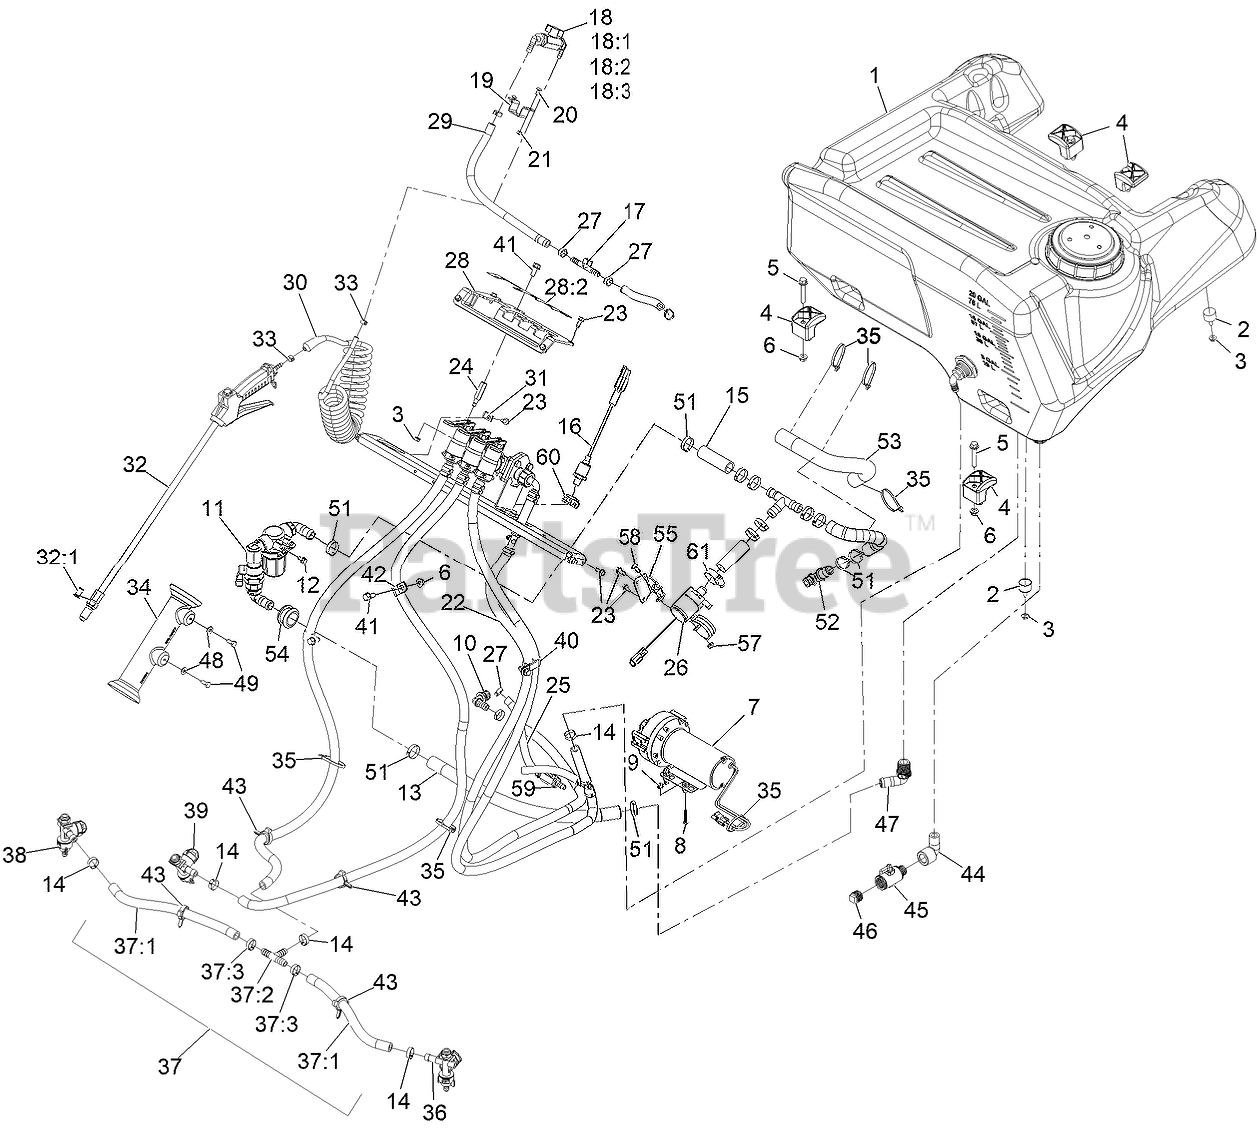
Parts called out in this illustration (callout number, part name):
1	Tank-Sprayer
5	SCREW-HHF
7	Pump-Diaphragm, 3.8 GPM
8	SCREW-SHWH
10	FITTING-ELBOW, BARBED
11	STRAINER ASM
12	SCREW-HHF
13	HOSE-WATER
14	CLAMP OETIKER 0.716"" CLOSED 0.826"" OPEN
15	ASM-, 3/4 Pvc Reinforced Water Hose
16	TRANSDUCER-PRESSURE
17	FITTING-TEE
18	Wand Control ASM
18:1	VALVE-BALL
18:2	FITTING-ELBOW-90
18:3	FITTING-ELBOW-90
19	BRACKET-VALVE
20	BOLT-CARR
21	NUT-LOCK, NI
23	SCREW-HWH
24	Spacer, Manifold Mount
25	Hose-Water
26	Pump-Centrifugal
28	COVER-CONTROLS
28:2	Decal-Lever Control
29	HOSE-WATER, 3/8 PVC RED
30	Hose-Coiled, 04X15Ft
31	CLAMP-R
32	SPRAY WAND ASM
32:1	STRAINER-NOZZLE, 50M 5PSI
34	HOLDER-WAND
35	TIE-CABLE
36	LEFT NOZZLE SUB ASM
37	HOSE ASM
37:1	HOSE-WATER
37:2	FITTING-TEE
37:3	CLAMP OETIKER 0.716"" CLOSED 0.826"" OPEN
38	RIGHT NOZZLE SUB ASM
39	CENTER NOZZLE SUB ASM
41	SCREW-HHF
42	CLIP-LOOM
43	CLAMP-HOSE
44	ELBOW-90 DEG
45	MICROVALVE
47	ELBOW-HOSEBARB
48	WASHER-FLAT
49	SCREW-HH
52	FITTING-ELBOW
53	SLEEVE-CORRUGATED, SPLIT
54	GROMMET
55	Brkt-Recir Pump
58	SCREW-CARR
59	Valve-3/8 Check
60	R-Clamp
61	CLAMP-HOSE
